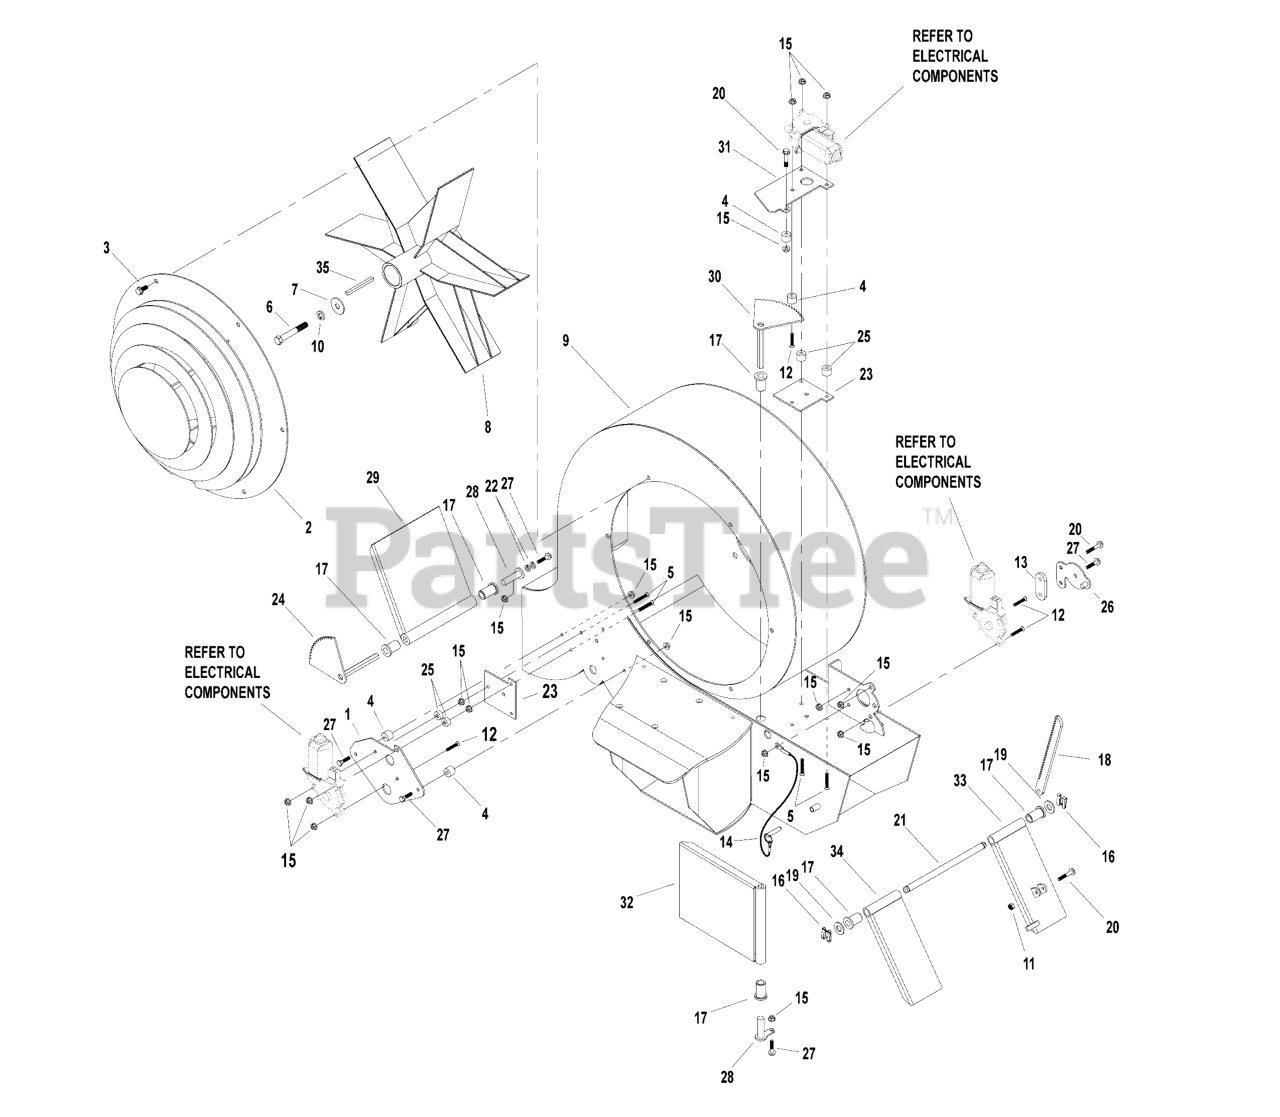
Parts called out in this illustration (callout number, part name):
1	PLATE, RIGHT DEFLECTOR COVER - BLK
2	WELD, SAFETY COVER Z3 - BLK
3	BOLT, 5/16-18 X 3/4, FLANGE, CZ
4	SPACER, .265 X .50 X .320, CZ
5	SCREW, 1/4-20 X 1-3/4, ALLEN, SS
6	BOLT, 5/8-18 X 2-1/4 GD8, PHOS
7	WASHER, 5/8 X 2" OD
7	WASHER, 7/16 (425-1091-2009)
8	IMPELLER, Z3 (ZF15018)
9	BLOWER HOUSING Z (ZFT15006)
10	WASHER, 5/8, SPLIT LOCK, CZ
11	NUT, 1/4-20, NYLOCK, YZ (15067)
12	SCREW, 1/4-20 X 1-1/4, ALLEN, SS
13	PLATE, RACK SPACER (101-16-2029)
14	Z DEFLECTOR PIN RETAINING CABLE (Pin & Lanyard Assembly)
15	NUT, 1/4-20, SERRATED FLANGE, YZ
16	CLIP, SAFETY
17	BUSHING, 1/2 X 3/4 X 1F
18	PLATE, DEFLECTOR RACK,CZ
19	WASHER, 1/2 SAE, YZ (15124)
20	BOLT, 1/4-20 X 1-1/2, FLANGE, CZ
21	ROD, DEFLECTOR SUPPORT, Z3000
22	WASHER, 1/4, LOCK, CZ (15080)
23	PLATE, DEFLECTOR SPACER (X310-2052)
24	WELD, UNIVERSAL DEFLECTOR GEAR
25	SPACER, .265 X .50 X .483, CZ
26	WELD, RACK KEEPER, CZ
27	BOLT, 1/4-20 X 3/4, FLANGE, CZ
28	PIN, DEFLECTOR, RIGHT
29	WELD, RIGHT DEFLECTOR, Z3000, CZ
30	WELD, UNIVERSAL DEFLECTOR GEAR
31	PLATE,FW DEFLECTOR MOTOR MNT (X310-2043)
32	WELD, FRONT DEFLECTOR, Z3000, CZ
33	WELD, LEFT POWER DEFLECTOR, Z3000, CZ
34	WELD, LEFT SLAVE DEFLECTOR, Z3, CZ
35	KEY, 3/8" SQ. X 4 (15055)
